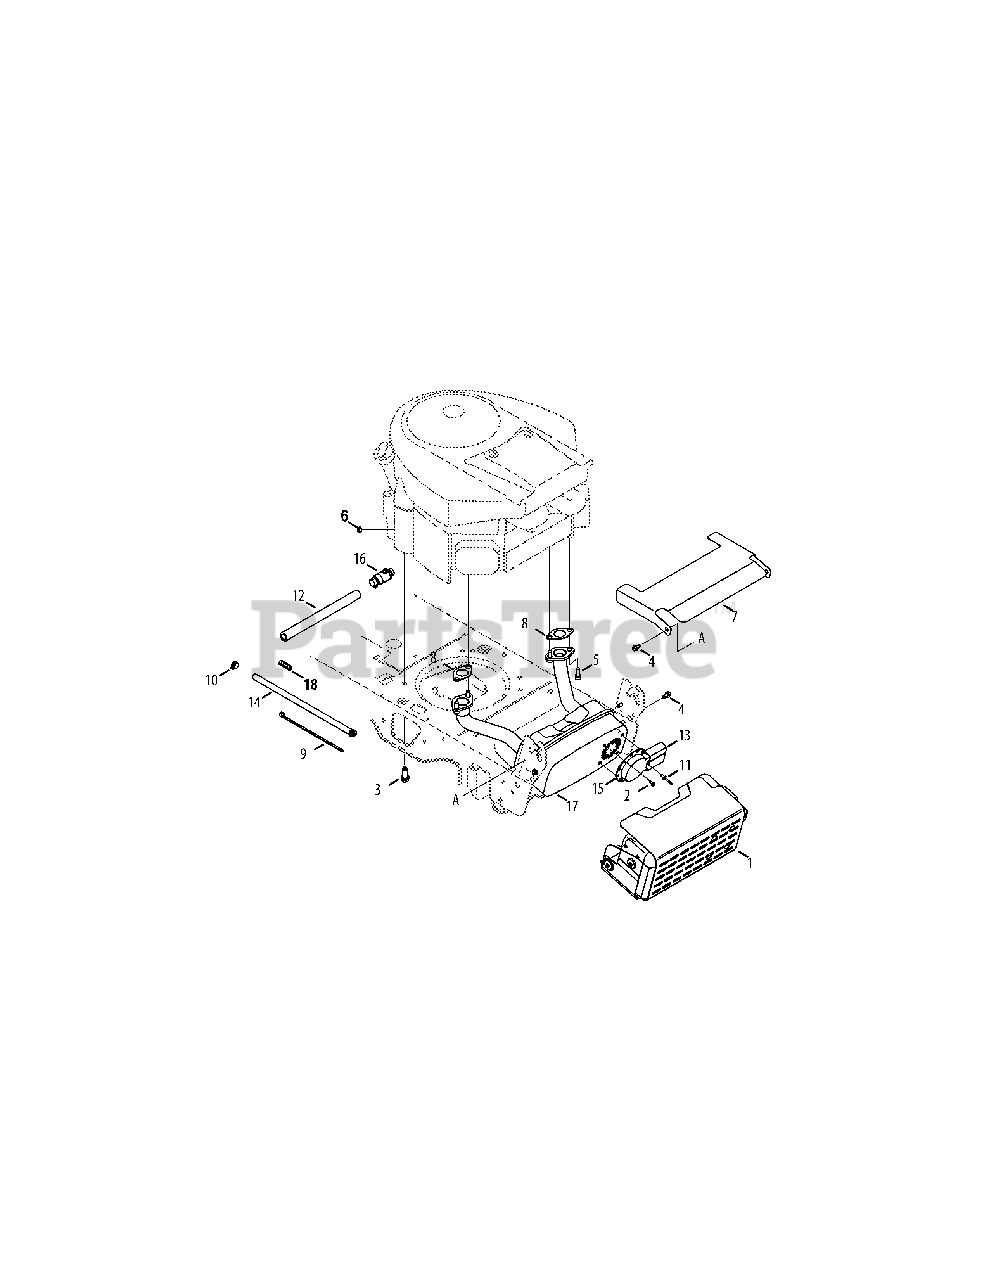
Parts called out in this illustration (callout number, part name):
1	Mulffler Shield Assembly
2	Screw, Indented Washer, #8-18:0.500
3	Taptite Screw, 3/8-16:1.000
4	Taptite Screw, 1/4-20:0.500
5	Socket Head Screw, 5/16-18:.750
6	Sems Nut, 1/4-20
7	Heat Shield
8	Exhaust Gasket
9	Cable Tie, 3/16 x .05 x 7.4
10	Hose Clamp, .490 DIA.
11	Rivet, .188 DIA x .300 L
12	Oil Drain Extension Hose
13	Muffler Deflector
14	Fuel Hose
15	Long Muffler Deflector, EPA
16	Oil Drain
17	Muffler
18	Hose Vent
